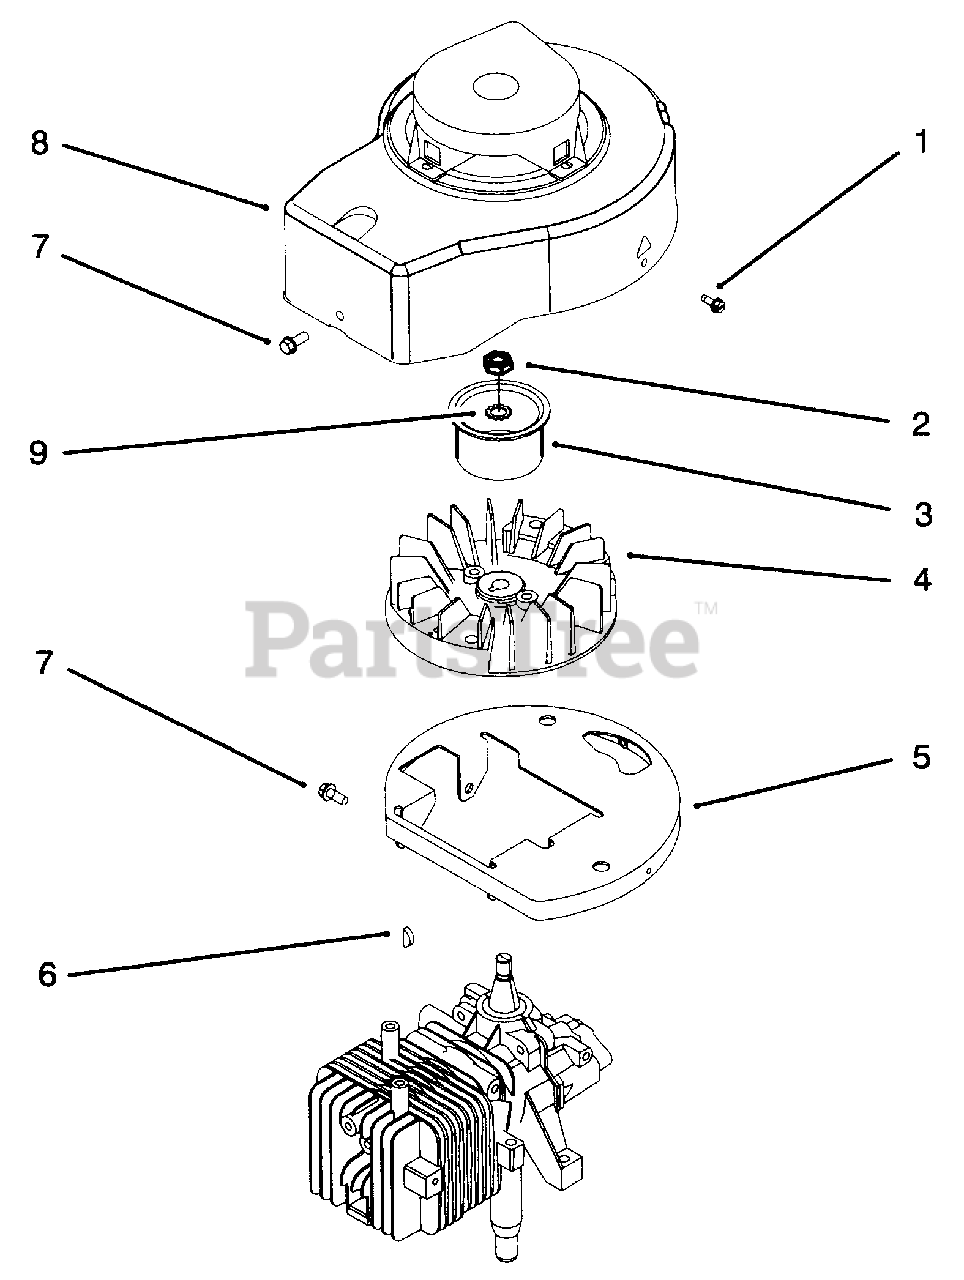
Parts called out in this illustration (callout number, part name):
3	Hub-Starter
4	Flywheel
5	Base-Shroud
7	Screw
8	Shroud Assembly
9	Washer-Lock
